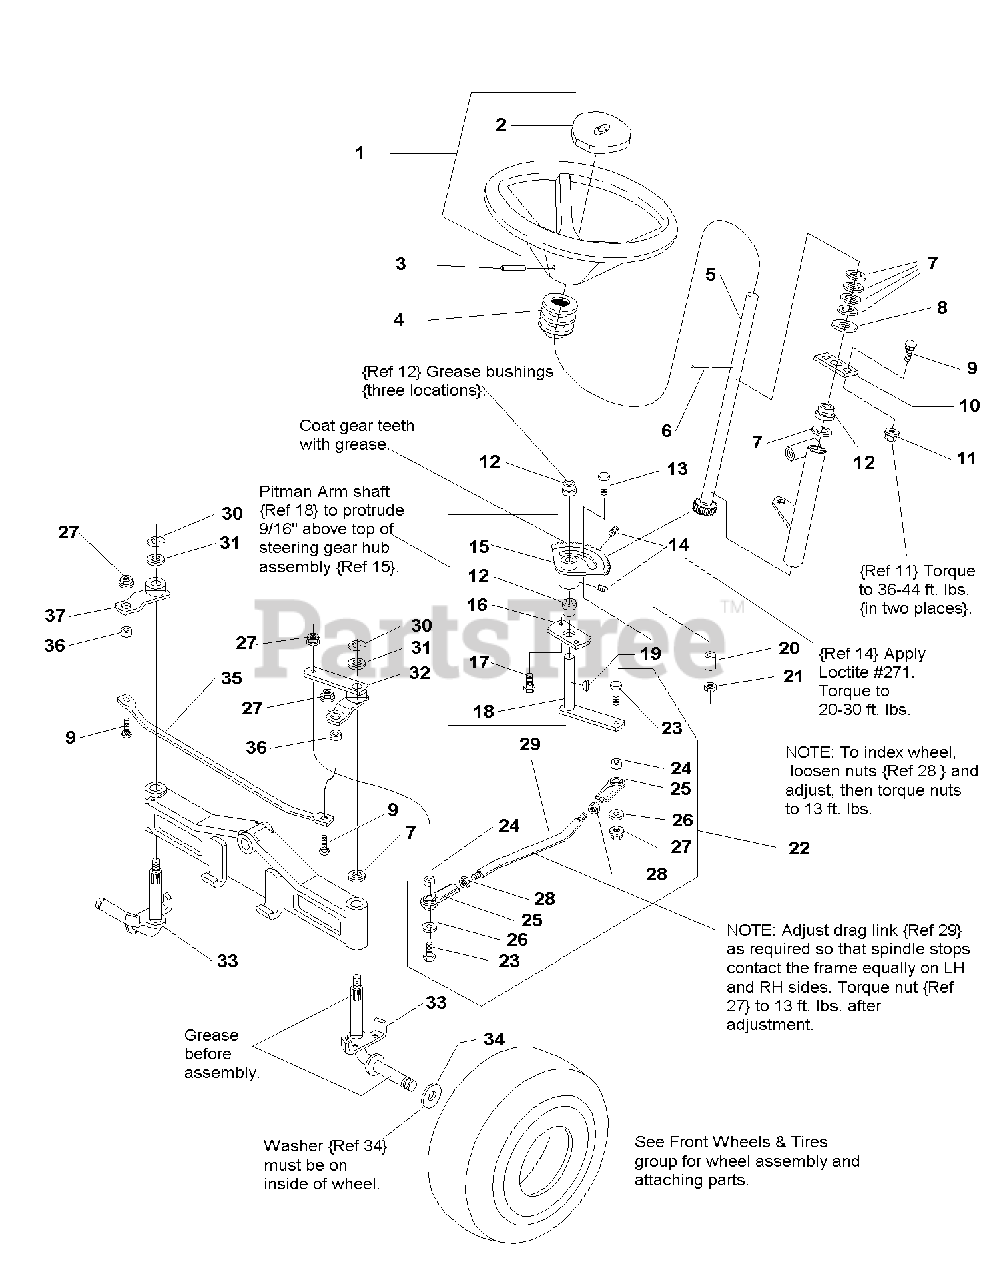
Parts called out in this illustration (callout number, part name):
1	STEERING WHEEL ASSEMBLY (Includes Ref. Nos. 2 & 3)
2	CAP, Steering Wheel
3	PIN, Spring, 5/8 x 2
4	TUBE, Steering
5	SHAFT ASSEMBLY, Steering
6	COTTER PIN, 3/16 x 1-1/4
7	WASHER, Plain, 49/64
8	WASHER, Plain
9	CARRIAGE BOLT, 3/8-16 x 1
10	PLATE, Mounting, Steering
11	NUT, Hex Flange, 3/8-16
12	BUSHING, Nylon
13	CAPSCREW, Hex Head, 5/16-18 x 1-1/2
14	SETSCREW, Square. Head, 5/16-18 x 1/2 G8
15	GEAR ASSEMBLY, Steering
16	SECTOR MOUNTING PLATE
17	CAPSCREW, Taptite, 5/16-18 x 1
18	PITMAN ARM ASSEMBLY
19	KEY, Hi Pro
20	SPACER, Stop
21	NUT, Hex Nylon Lock, 5/16-18
22	DRAG LINK KIT, (Includes Ref. Nos. 23, 24, 25, 26, 27, 28 & 29)
23	CAPSCREW, Hex Head, 3/8-16 x 1-3/8
25	BALL JOINT, Flat
26	WASHER, Plain, 3/8
27	NUT, Hex Flange, 2-Way Lock, 3/8-16
28	NUT, Hex Jam, 1/2-20
30	KLIP RING, 5/8
31	WASHER, 5/8
32	STEERING ARM ASSEMBLY, LH, Splined
33	SPINDLE ASSEMBLY, Splined (with welded cup washer)
34	WASHER, Special
37	STEERING ARM ASSEMBLY, RH, Splined
